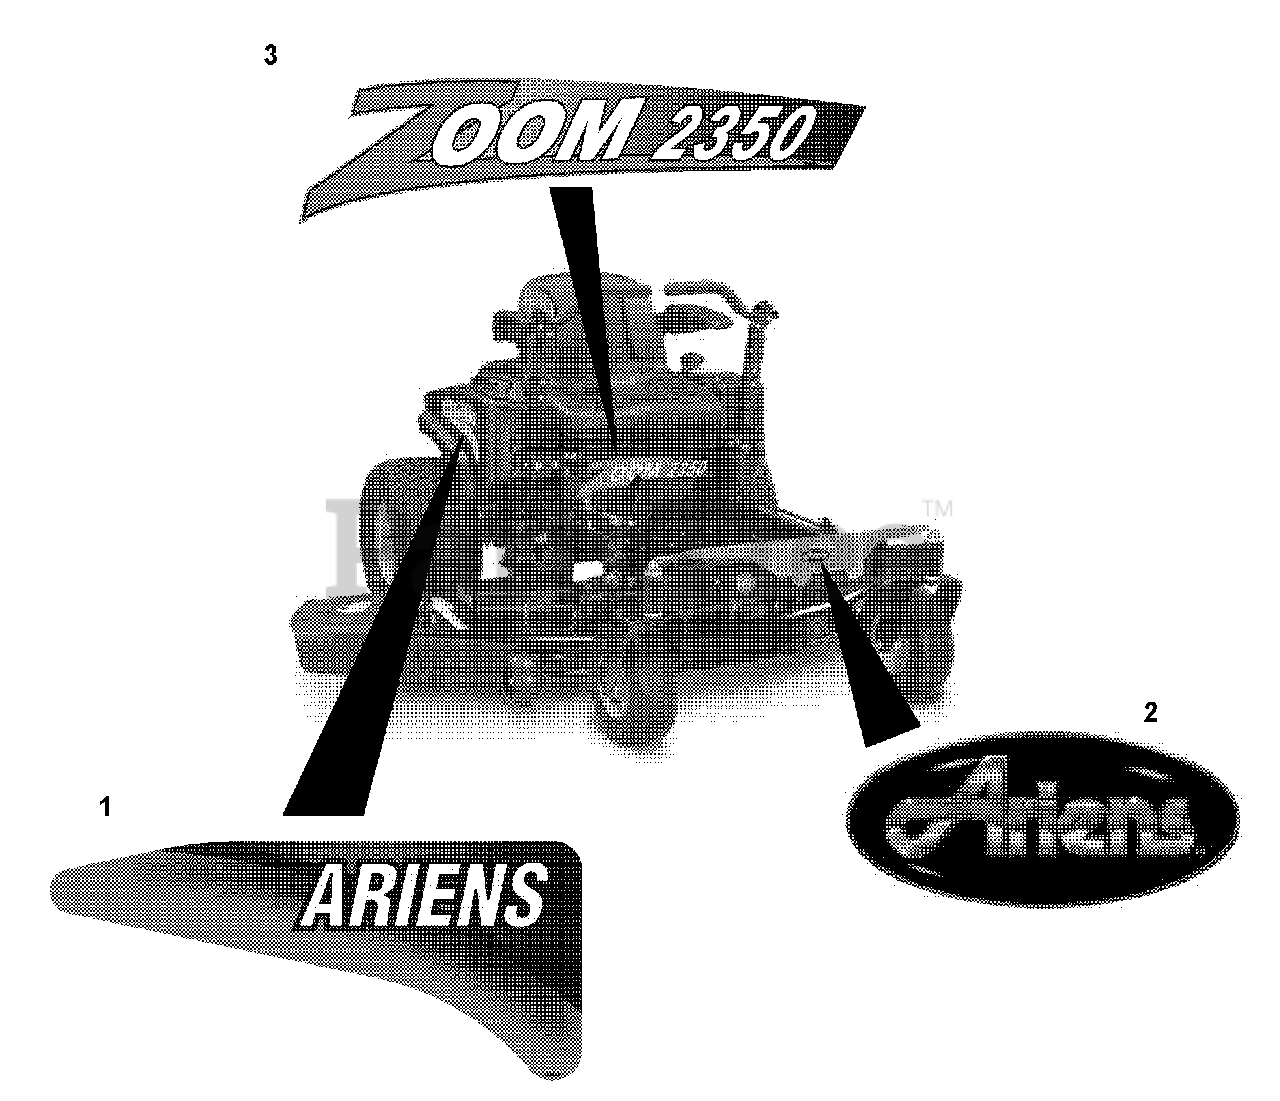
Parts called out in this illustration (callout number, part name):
1	DECAL, RH ARIENS ZOOM TANK
2	DECAL-ARIENS JEWEL
3	DECAL, 2350 ZOOM
